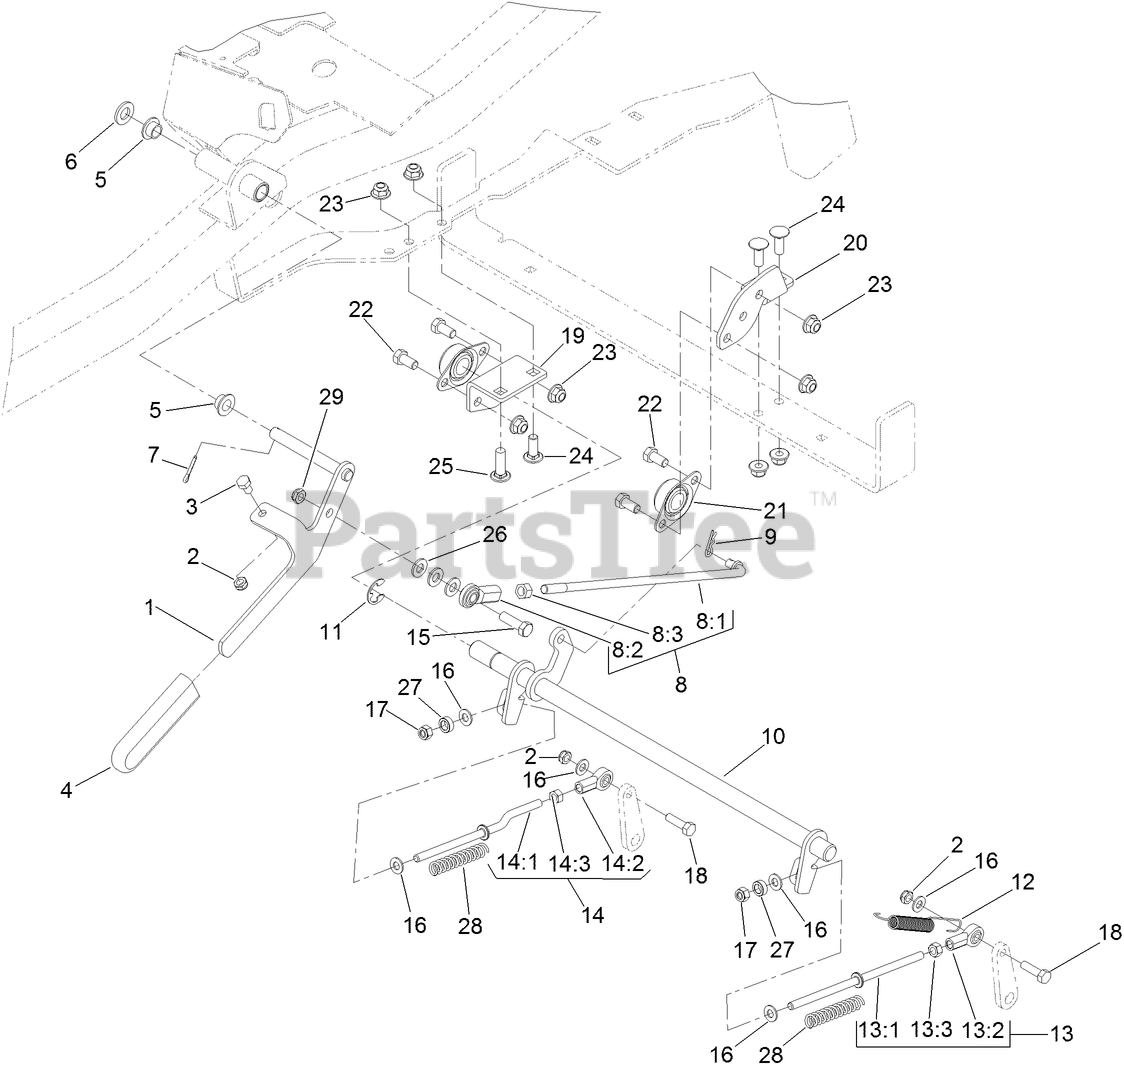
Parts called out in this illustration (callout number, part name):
1	HANDLE-BRAKE
2	NUT-LOCK, NI
3	SCREW-HH
4	GRIP-LEVER
5	BEARING-CONTROL
6	WASHER-FLAT
7	PIN-COTTER
8	BRAKE LINK ASM
8:1	ROD-LINK, BRAKE
8:2	JOINT-BALL, END
8:3	NUT-HEX
9	PIN-COTTER
10	SHAFT-BRAKE
11	E-RING
12	SPRING-EXTENSION
13	LH BRAKE ROD ASM
13:1	ROD-BRAKE
13:2	BALLJOINT-RH
13:3	NUT-HEX
14	RH BRAKE ROD ASM
14:1	ROD-BRAKE
14:2	BALLJOINT-RH
14:3	NUT-HEX
15	SCREW-HH
16	WASHER-PLAIN
17	NUT-LOCK
18	SCREW-HH
19	BRACKET-SHAFT MOUNT, RH
20	BRACKET-SHAFT MOUNT, LH
21	BEARING-FLANGE, SIDE
22	SCREW-HH
23	NUT-HF, NI
24	SCREW-CARR
25	SCREW-CARR
26	WASHER-FLAT
27	SPACER
28	SPRING-RETURN, NEUTRAL
29	NUT-LOCK, NI
